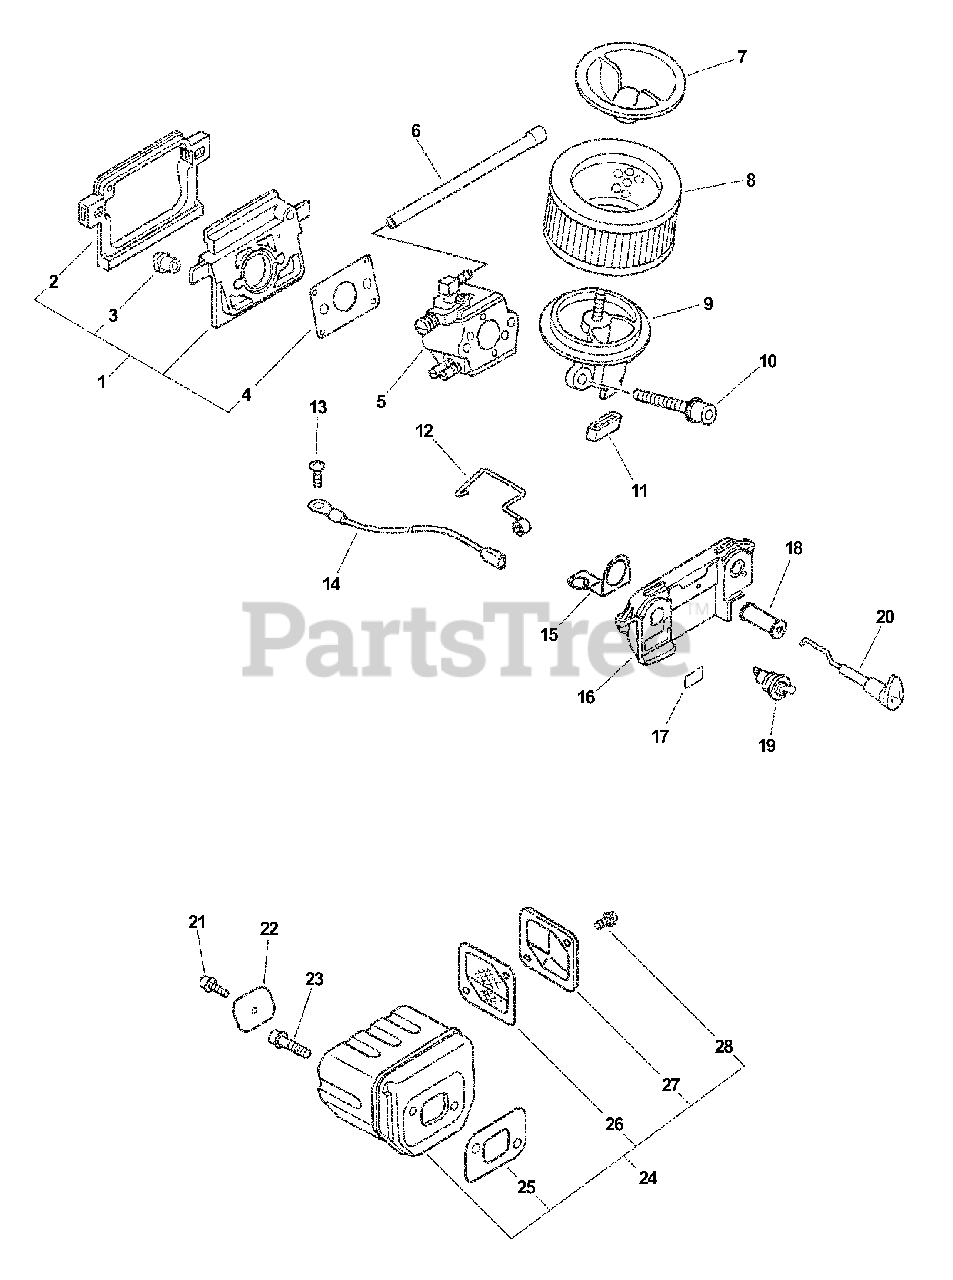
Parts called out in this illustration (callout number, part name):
1	INSULATOR KIT
2	CUSHION
4	GASKET, INTAKE
5	CARBURETOR
6	PIPE - IMPULSE
7	COVER, AIR FILTER
8	FILTER, AIR
9	ADAPTOR, INTAKE
10	SCREW - 5X50
12	ROD, THROTTLE
13	SCREW - 4X6
14	LEAD - GROUND
15	TERMINAL - GROUND
16	BRACKET, SWITCH
17	LABEL - STOP
18	GROMMET
19	IGNITION SWITCH ASSY
20	ROD, CHOKE
21	SCREW - 4X6
23	SCREW - 5X14
24	MUFFLER ASSY
25	GASKET, EXHAUST
26	SCREEN, SPARK ARRESTOR
27	GUIDE, EXHAUST
28	SCREW - 4X8
